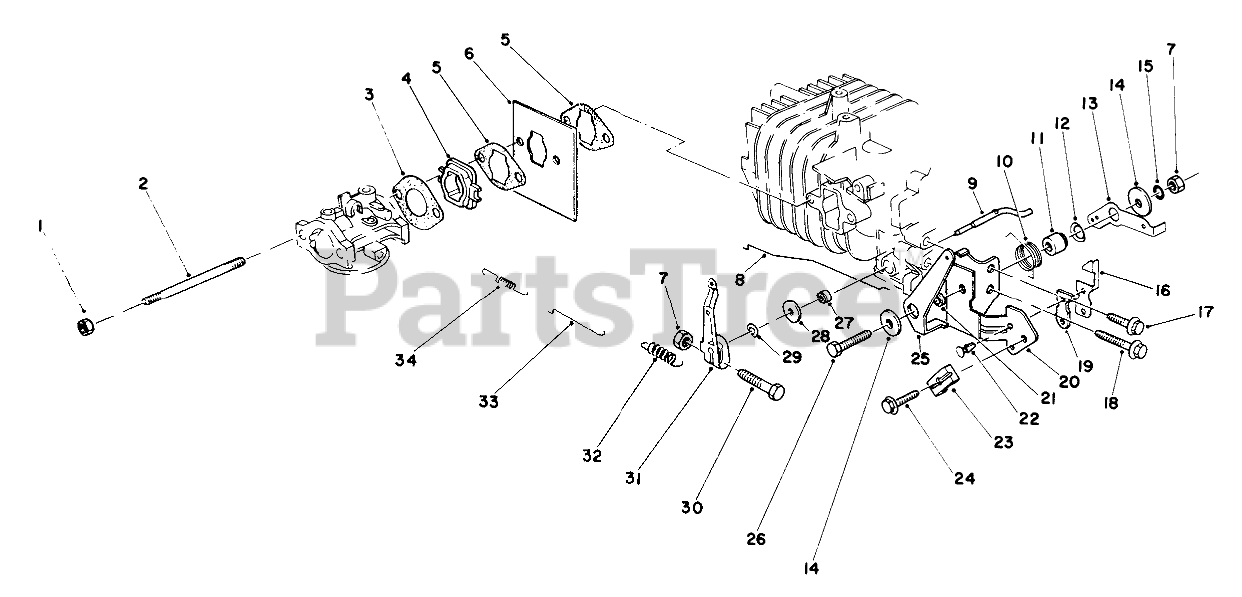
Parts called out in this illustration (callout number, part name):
1	NUT-LOCK
2	CARB STUD BOLT
3	GASKET-CARB
4	INSULATOR
5	GASKET
6	SHIELD
8	CHOKE ROD
9	Shaft-Govemor
10	Spring-Choke Control Lever
11	Gov Lever Spacer
12	Washer-Gov. Spring Lever
13	GOV SPRING LEVER
14	WASHER
15	LOCKWASHER
16	TERMINAL-KILL SWITCH
19	INSULATOR-KILL SWITCH
20	Bracket-Throttle Control
21	Spacer-Choke Control Lever
22	KILL SWITCH RIVET
23	CLAMP-CABLE
25	LEVER-CONTROL, CHOKE
27	SEAL-OIL
28	WASHER
29	E-RING
31	Lever-Throttle Control
32	Spring-Governor
33	ROD-CARBURETOR
34	SPRING
